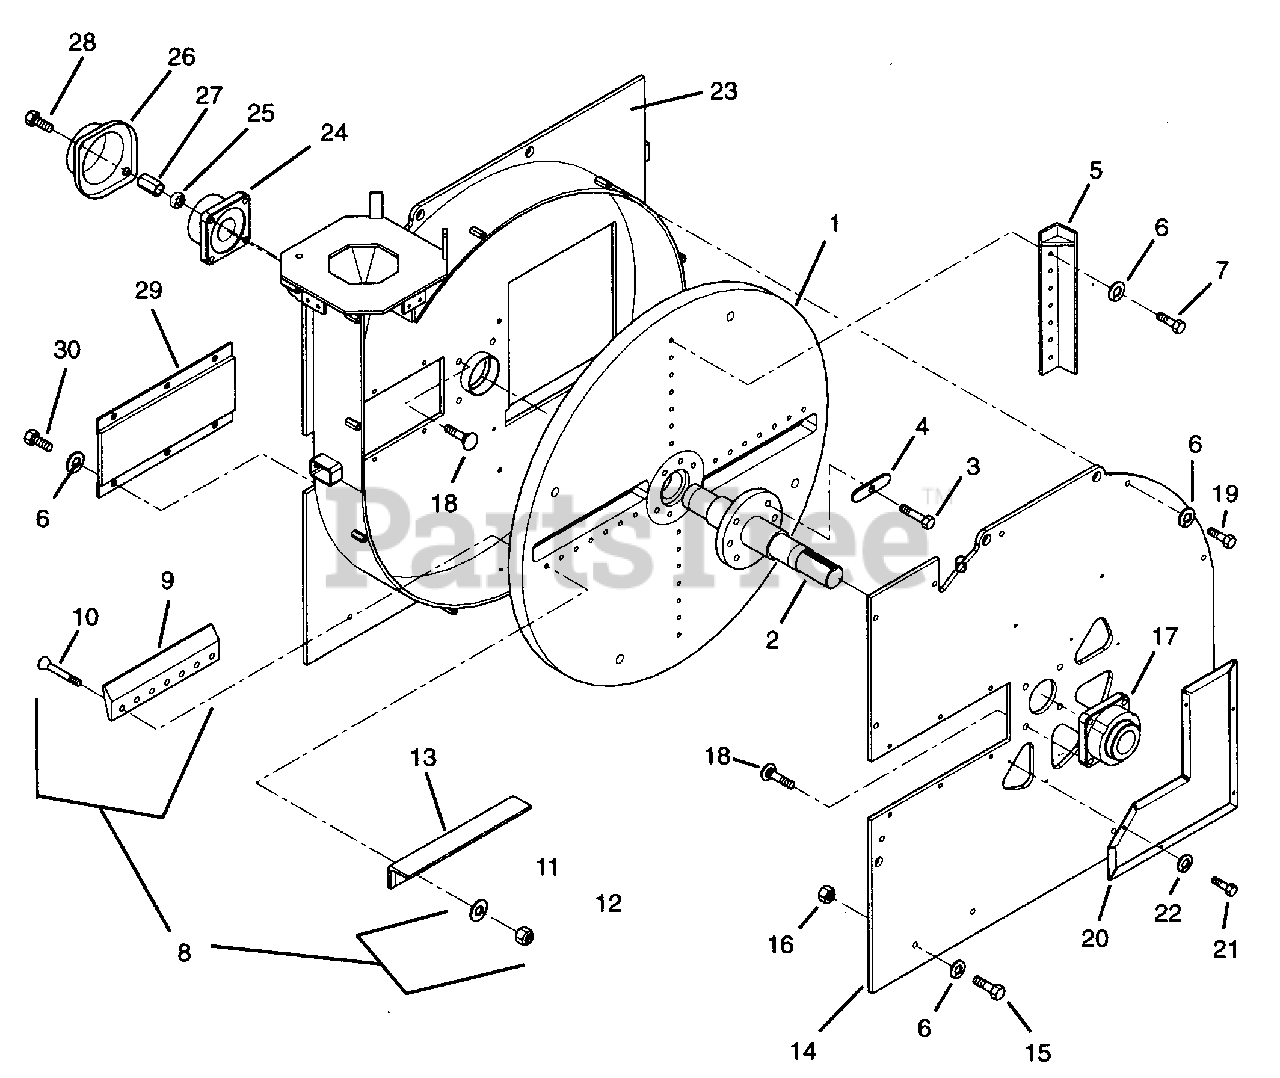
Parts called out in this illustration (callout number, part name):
1	Flywheel
2	Flywheel Shaft Weldment
3	Bolt-Hex .62-11 x 2.25 Grade 8
4	Lock Tab
5	Impeller Weldment
6	Washer-Lock .500 x .151
7	Bolt-Hex .50-13 x 1.25 Grade 5
8	Chipper Knife Set 495(Contains Items 9-12)
9	Cutter Knife
10	Screw-Socket Head .50-13 x 3.5 Grade 8
11	Washer-Flat-Steel .568 x 1.750 x .219
12	Nut-Locking-Crown .50-13
13	Impeller Weldment
14	Housing(Front)
15	Bolt-Hex .50-13 x 1.75 Grade 8
16	Nut-Locking-Crown .50-13
17	Bearing-Flange 2.00
18	Rib Neck Bolt
19	Bolt-Hex .50-13 x 1.75 Grade 8
20	Screen Frame Weldment
21	Bolt-Hex .31-18 x 1.00 Grade 5
22	Washer-Lock .313 x .078
23	Housing(Rear)
24	Bearing-Flange 2.00 Inside Diameter,Non-Expandable
25	Nut-Locking Flex
26	Bearing Cover
28	Bolt .625-18 x .875
29	Access Cover Weldment
30	Bolt-Hex .50-13 x 1 Grade 5
